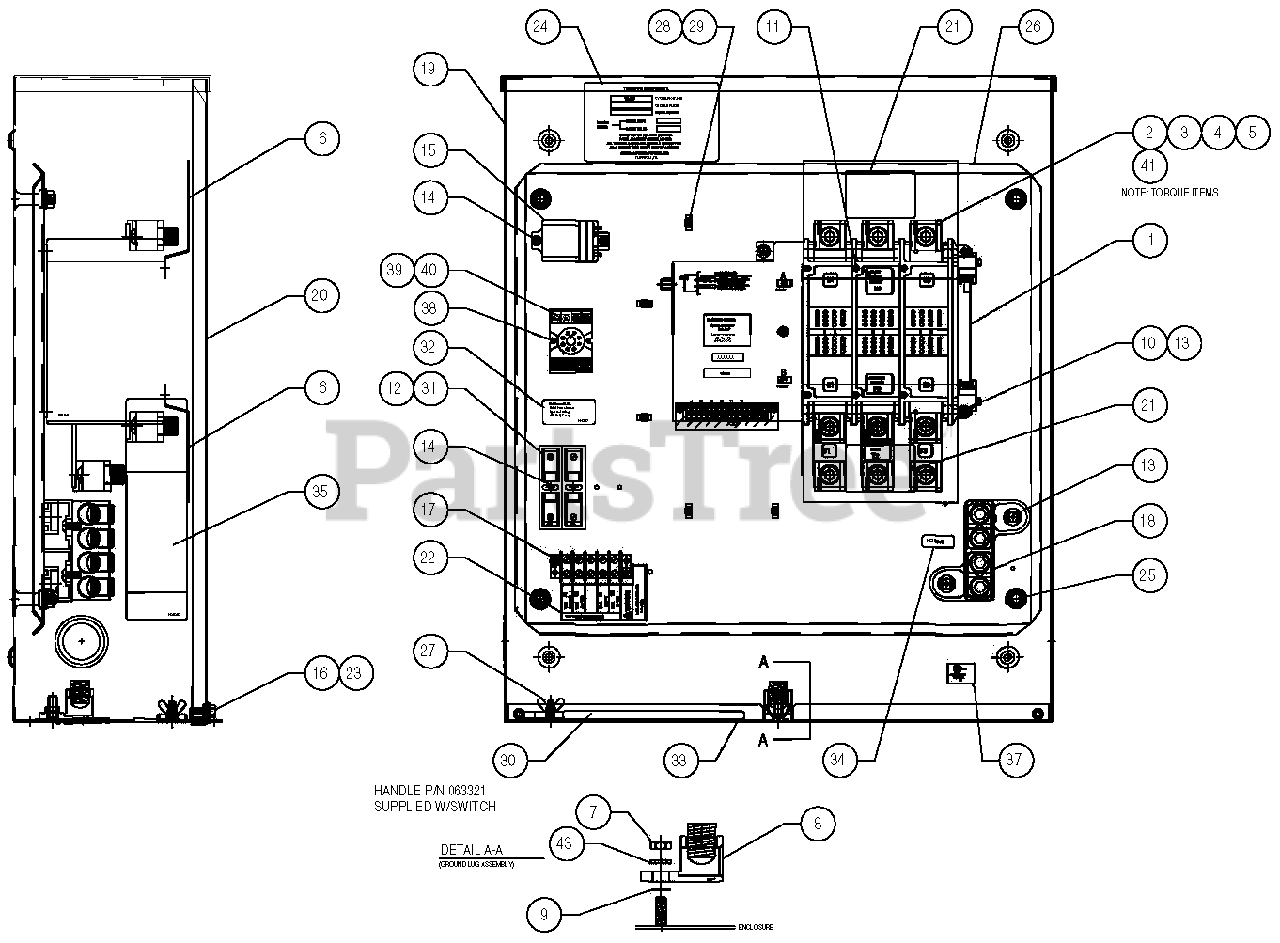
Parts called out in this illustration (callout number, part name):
1	XFER SW-W 200A600V3P
2	LUG SLDLSS 400-#4X1/4-20 CU7AL
3	SCREW FHM M8-1.25 X 20MM CR
4	NUT LOCK FL M8-1.25 YEL CHR
5	SCREW HHTT #8-32 X 1/4 CZ
6	COVER LUG 3P 150/200AMP
7	NUT HEX M8-1.25 G8 CLEAR ZINC
8	LUG SLDLSS 350-#6X13/32 AL/CU
9	WASHER SHAKEPROOF EXT 5/16 STL
10	WASHER LOCK M6-1/4
11	SCREW PPHM DSEMS M4-7 X 10 ZNC
12	FUSE HOLDER
13	SCREW HHTT M6-1.0 X 12 ZINC
14	SCREW HHTT M4-0.7 X 10 BP
15	RELAY PNL 12VDC DPDT 10A@240VA
16	SCREW HHC M6-1.0 X 16 G8.8
17	RIVET POP .156 X .675 AL
18	ASS'Y-NTRL BL150-200A
19	WELDMENT,TRANSFER SWITCH BOX
20	COVER, TRANSFER SWITCH BOX
21	DECAL TERMINAL SHOCK HAZARD
22	DECAL TERMINAL STRIP
23	WASHER M6 NYLON
24	DECAL,SWITCH RATING
25	NUT LOCK FL 3/8-16
26	SUBPLT 200A TS 3R
27	NUT WING M6-1.0
28	HOLDER CABLE TIE
29	TIE WRAP UL 5.6 X .10 NATL
30	HANDLE XFER SWITCH 1-400A
31	FUSE 5A X BUSS
32	DECAL, FUSE REPLACEMENT
33	DECAL GROUND LUG
34	DECAL NEUTRAL
35	DECAL, MANUAL OPERATION
36	DECAL,TEST SEQUENCE 2P TS 3R
37	DECAL-UL LIST HSB
38	SCREW SWAGE 8-32 X 1/2 Z/YC
39	3-PHASE POWER MONITR
40	SOCKET RELAY OCTAL 8P 300V-10A
41	DECAL,LUG TORQUE INFO
42	DECAL TRANSFER SWITCH RTS
43	WASHER LOCK M8-5/16
